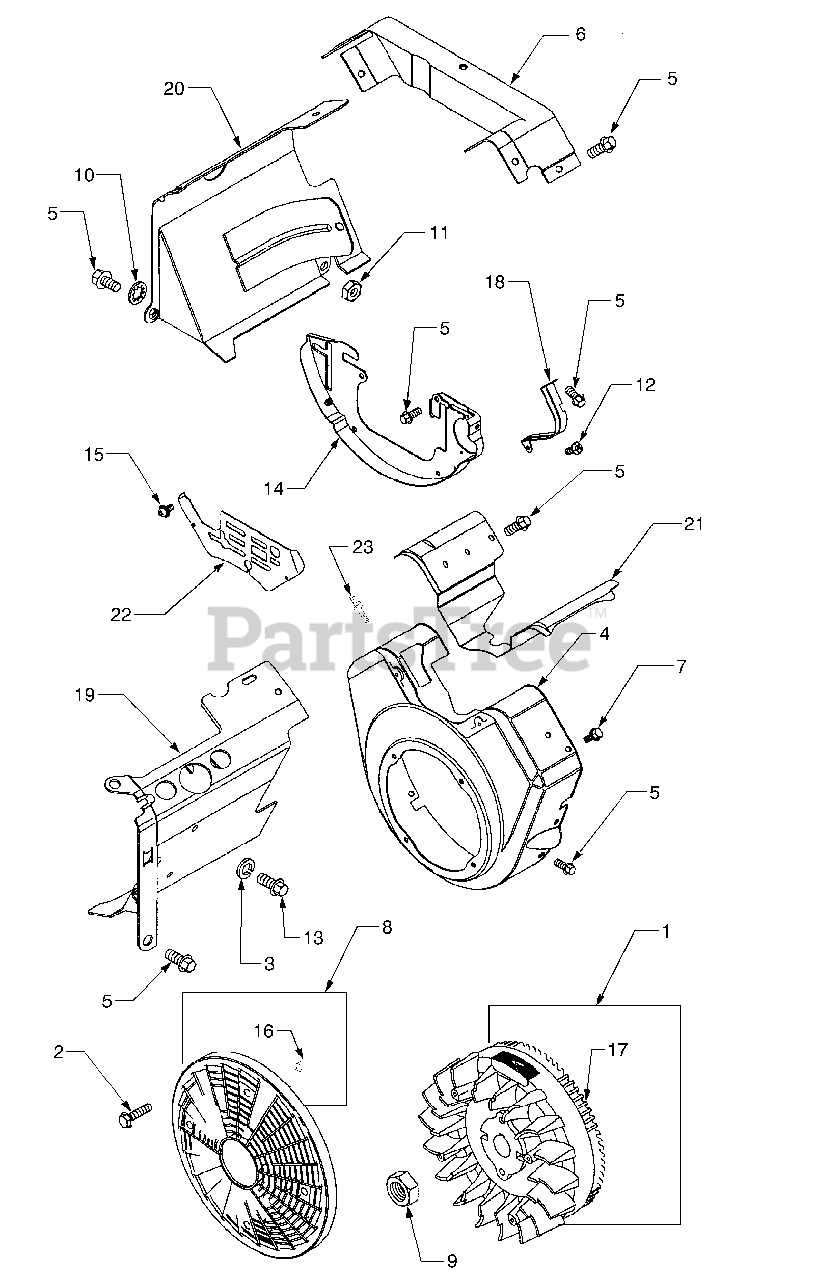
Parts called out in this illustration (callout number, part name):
2	Screw, Hex
3	Washer, Lock
4	Housing, Blower
5	Screw, Hex
6	Cover, Air Guide
7	Screw, Hex
8	Screen, Rotating
10	Washer, Lock
11	Nut, Hex
12	Screw, Hex
13	Screw, Hex
14	Plate, Back
15	Screw, Hex
16	Spacer
17	Gear, Ring
18	Guard, Flywheel
19	Cover, Air Guide (Cylinder #1)
20	Cover, Air Guide (Cylinder #2)
21	Cover, Valley
22	Cover, Carburetor
23	Fitting, Hose Barb
